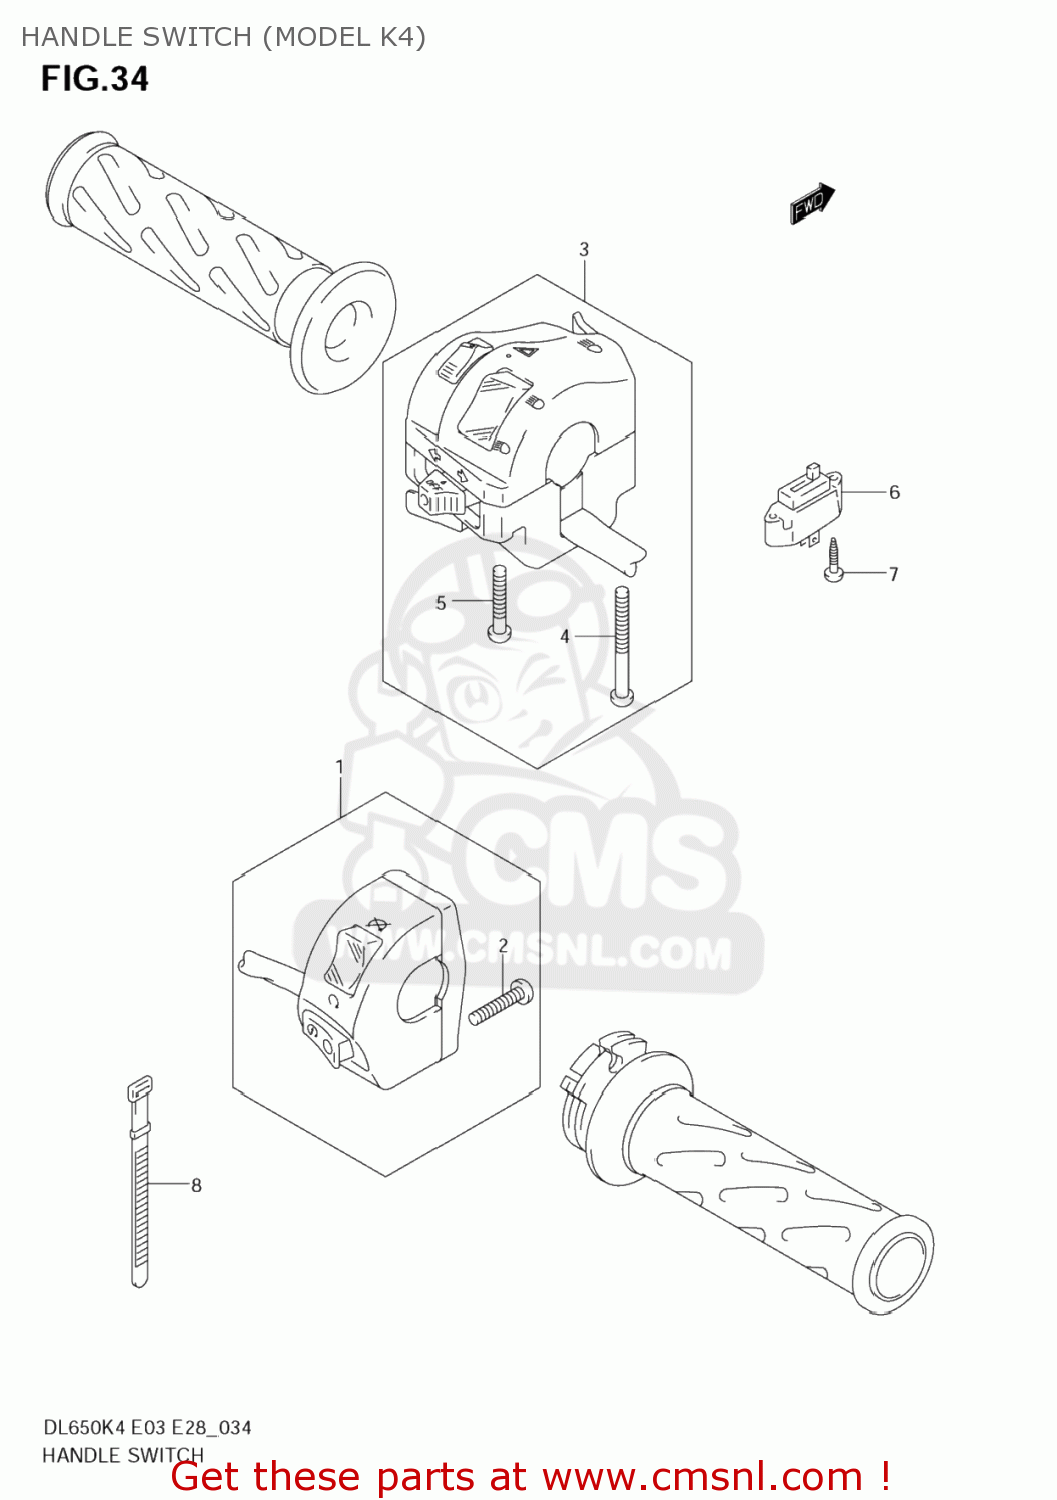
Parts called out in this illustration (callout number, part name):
1	SWITCH ASSY,HANDLE,R
2	SCREW
3	SWITCH ASSY,HANDLE,L
4	SCREW
5	SCREW
6	SWITCH ASSY,CLUTCH
7	SCREW(3X14)
8	CLAMP(L:120)
